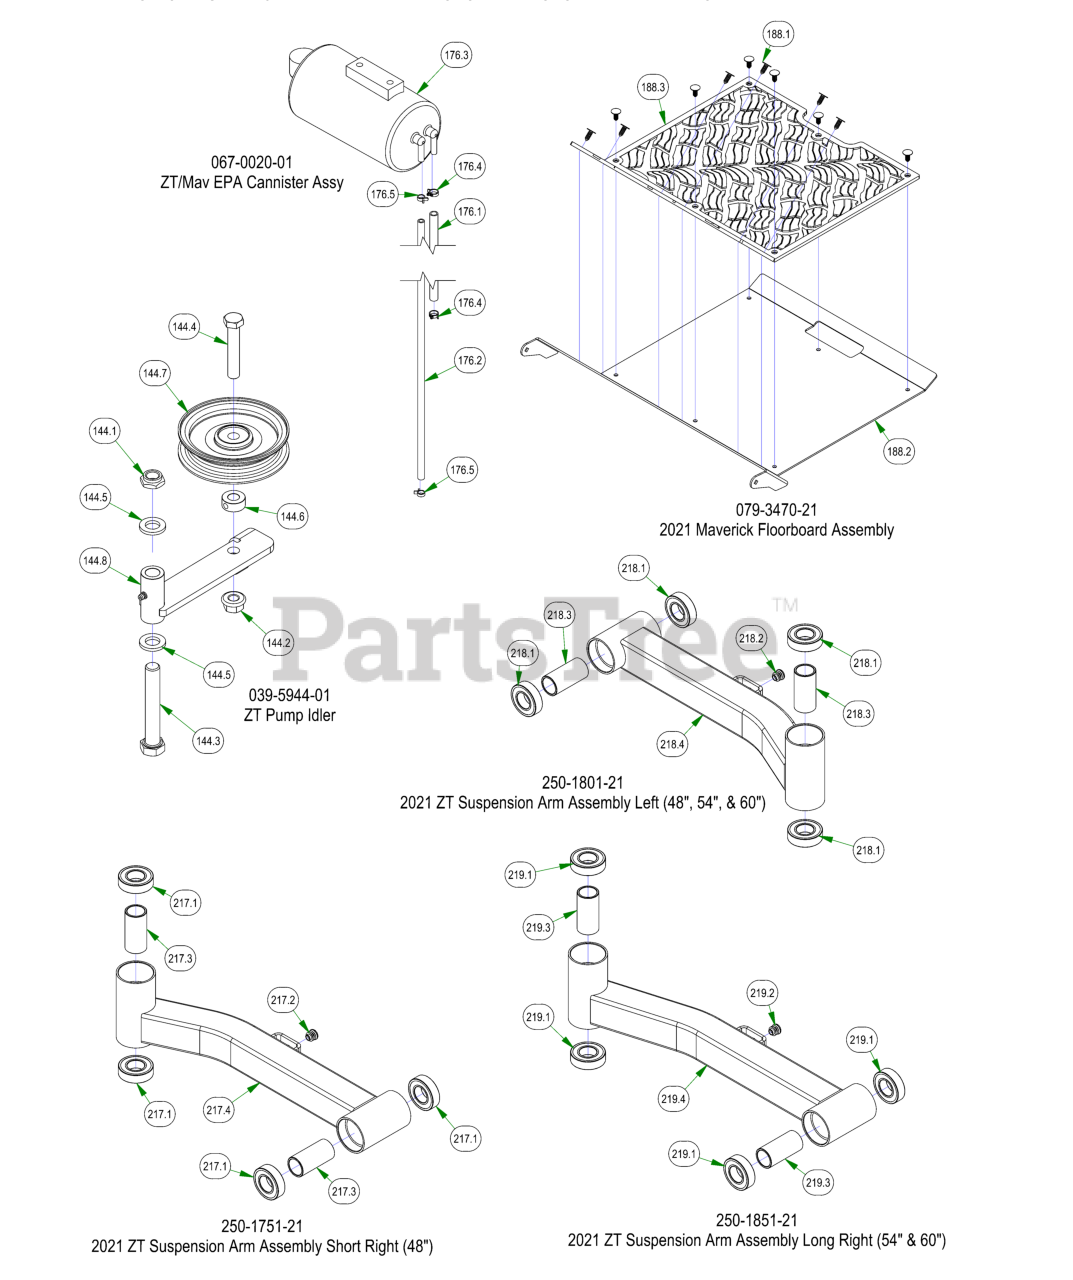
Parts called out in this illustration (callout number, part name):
144	ZT Pump Idler
144.1	5/8-11 NYLON INSERT JAM LOCKNUT ZINC
144.2	1/2-13 NYLON INSERT FLANGE LOCKNUT ZINC
144.3	5/8-11 X 4 HEX CAP SCREW (GR.8) ZINC YELLOW
144.4	1/2-13 X 2-3/4 HEX CAP SCREW (GR.5) ZINC
144.5	.635 ID X 1.120 OD X .140 THICK FLAT WASHER NYLON
144.6	1/2 SOLID SHAFT COLLAR (W/1 SET SCREW) ZINC
144.7	4 3/4" Idler Pulley
144.8	Pump Idler Bracket
176	ZT/Mav EPA Cannister Assy
176.1	1/4" Vinyl Tubing, 46" Long
176.2	3/16" Vinyl Tubing, 55" Long
176.3	Carbon Canister
176.4	3/16 Vinyl Clamp
176.5	3/16" Vinyl Hose Clamp
188	2021 Maverick Floorboard Assembly
188.1	Ratchet Fastener
188.2	2018 Maverick Floorboard
188.3	2021 Maverick Floor Mat W/ Reaper Tread
217	2021 ZT Suspension Arm Assembly Short Right (48")
217.1	1641 BEARING W/2 CONTACT RUBBER SEALS
217.2	5/8 Round Insert
217.3	2016 Front Bearing Spacer
217.4	2021 ZT RH Front Arm - Short
218	2021 ZT Suspension Arm Assembly Left (48", 54", & 60")
218.1	1641 BEARING W/2 CONTACT RUBBER SEALS
218.2	5/8 Round Insert
218.3	2016 Front Bearing Spacer
218.4	2021 ZT LH Front Arm
219	2021 ZT Suspension Arm Assembly Long Right (54" & 60")
219.1	1641 BEARING W/2 CONTACT RUBBER SEALS
219.2	5/8 Round Insert
219.3	2016 Front Bearing Spacer
219.4	2021 ZT RH Front Arm - Long
